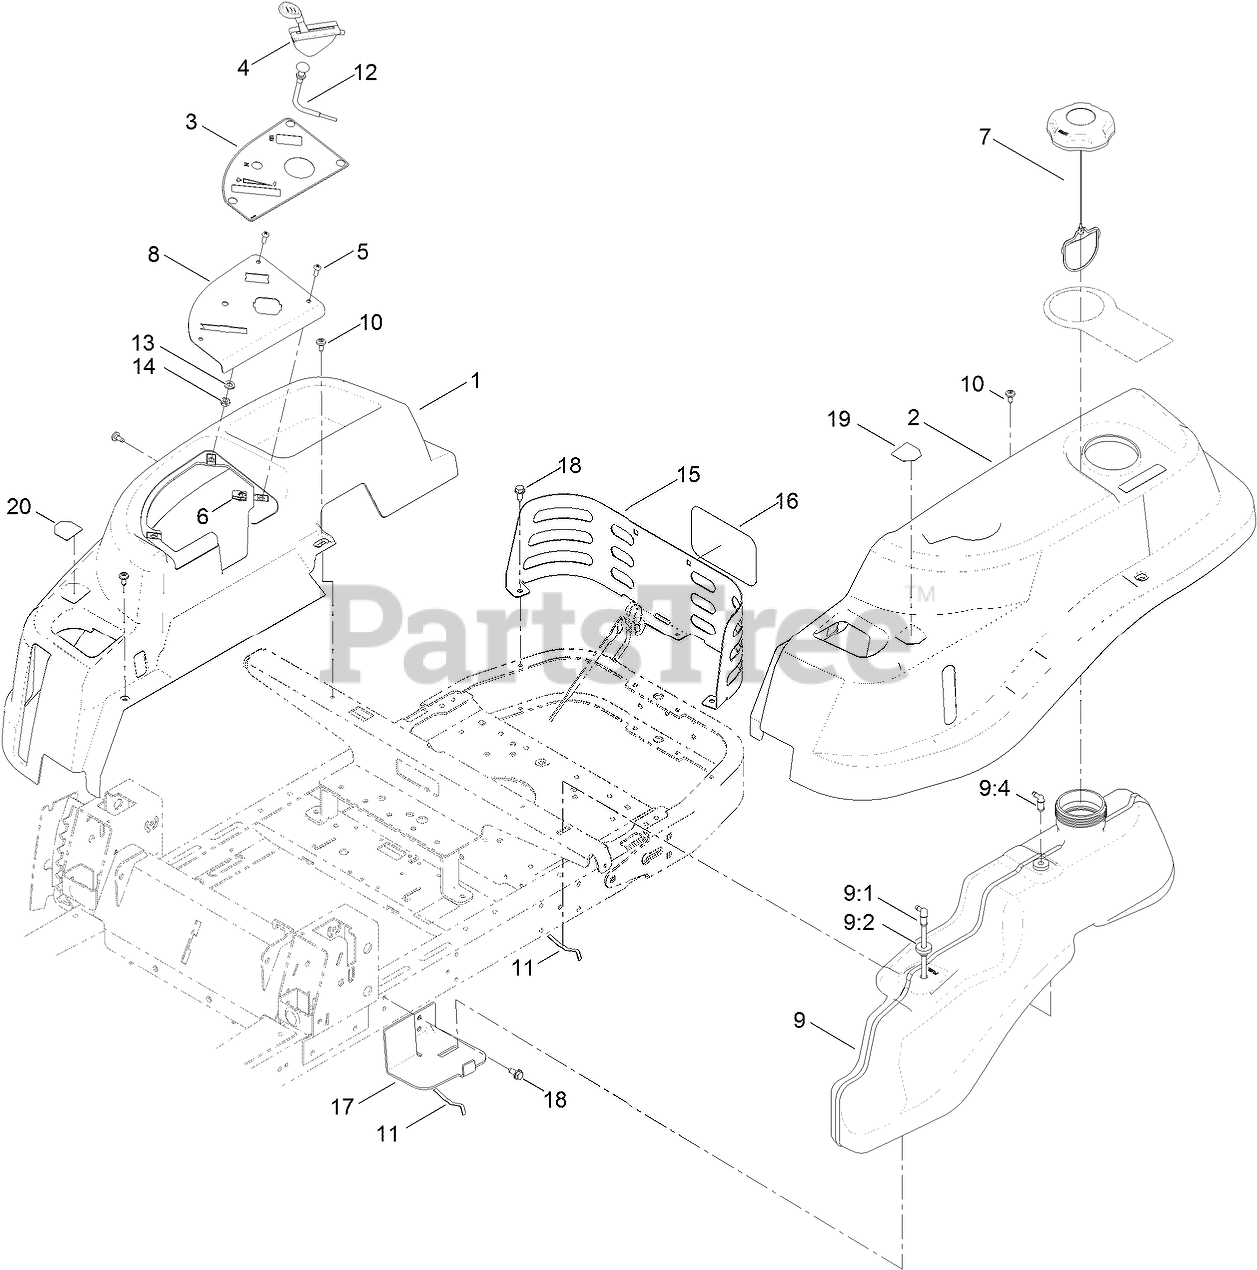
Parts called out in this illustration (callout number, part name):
1	POD-RH
2	POD-LH
3	DECAL-PANEL, CONTROL
4	CABLE-THROTTLE
5	SCREW-PRH
7	CAP-FUEL, RATCHETING
8	PLATE-CONTROL
9	FUEL TANK ASM
9:1	CONNECTOR-ELBOW, 90 DEG
9:2	BUSHING
9:4	FITTING-PLASTIC
10	SCREW-SHOULDER
11	SPRING
12	CABLE-CHOKE
13	WASHER-LOCK
14	NUT-HJ
15	GUARD-REAR
16	DECAL
17	SUPPORT-TANK, FRONT
18	SCREW-HWHTF
19	DECAL-CONTROL LEVER, LH
20	DECAL-CONTROL LEVER, RH
